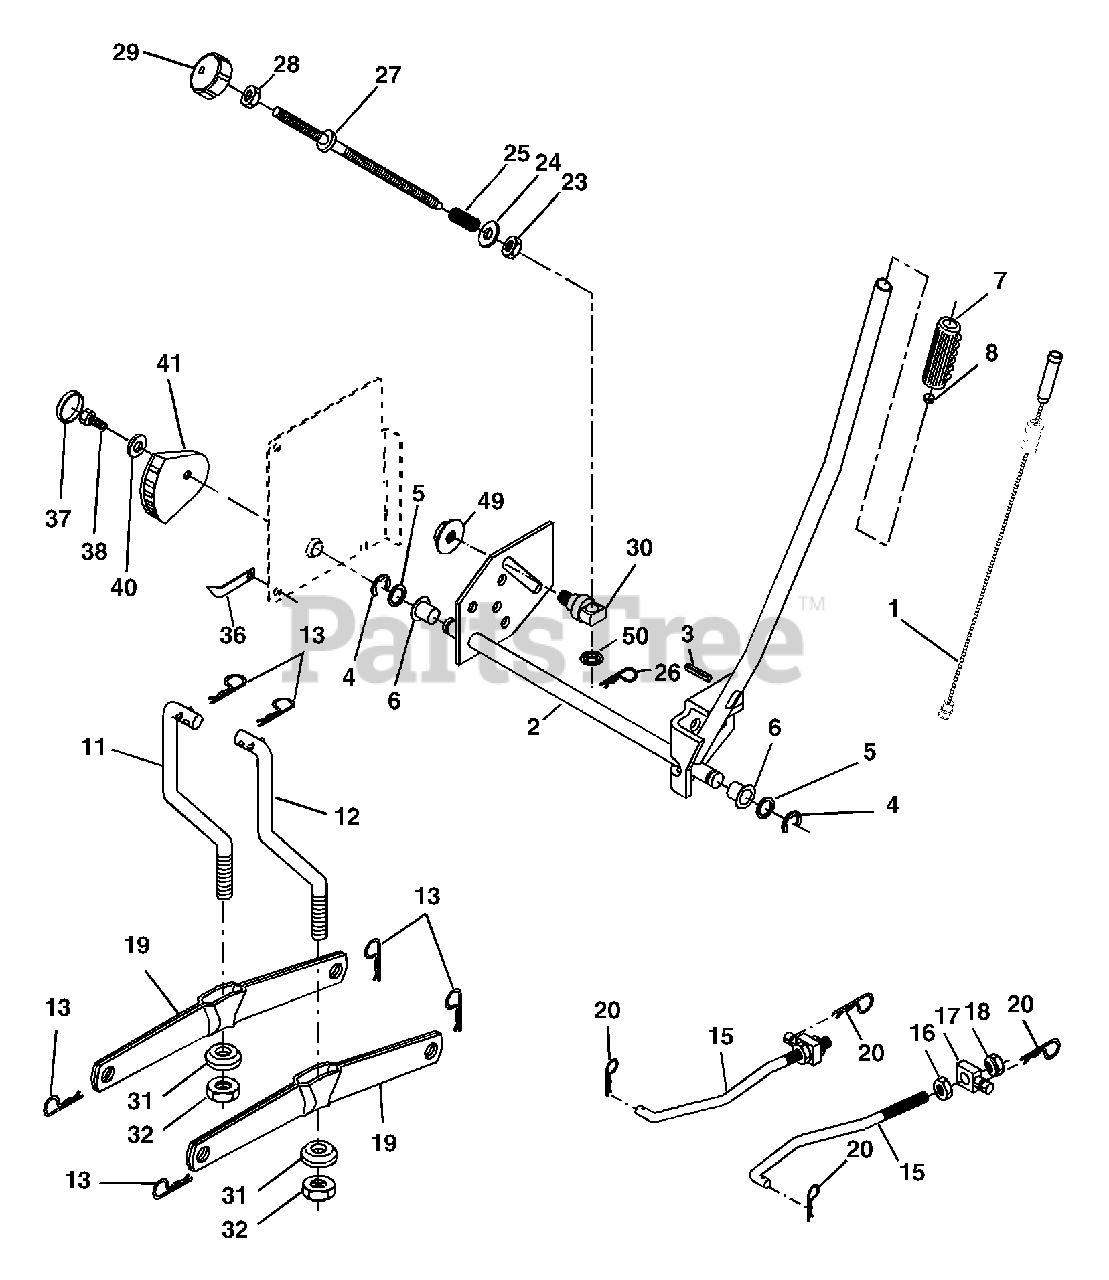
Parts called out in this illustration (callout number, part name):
1	Wire Asm Inner/Spring W/Plunger LT
2	Shaft Asm Lift RH w/Inf
3	Pin Groove 1 500 Zinc
4	E Ring #5133-62
5	Washer 21/32 x 1 x 21 Ga.
6	Bearing Nylon Blk 629 Id
7	Grip Handle Fluted Blk
8	Button Plunger Black
11	Link Lift LH
12	Link Lift RH
13	Retainer Spring
15	Link Front
16	Nut Jam Hex 1/2-13 unc
18	Nut Lock w/Wsh 1/2-13 unc
19	Arm Suspension Rear
20	Retainer Spring
23	Nut Special
24	Washer 13/32 x 5/8 x 16 Ga.
25	Spring 2-1/8"
26	Retainer Clip
27	Rod Adj Lift Zinc 7.49 Wrk Lg
28	Nut Hex Jam 3/8-16 unc
29	Knob Inf 3/8-16 Unc Blk W/sym
30	Trunnion Infin Height
31	Bearing PVT Lift
32	Nut Crownlock 3/8-24
36	Indicator Height STLT
37	Plug Hole Blk 1.485/1.515 Dia.
38	Screw 5/16-18 x 1
40	Washer 11/32 x 1-1/2 10 Ga.
41	Scale Ind. Height Blk.
49	Nut Hex Flange Lock
50	Nut, Push Phos & Oil
